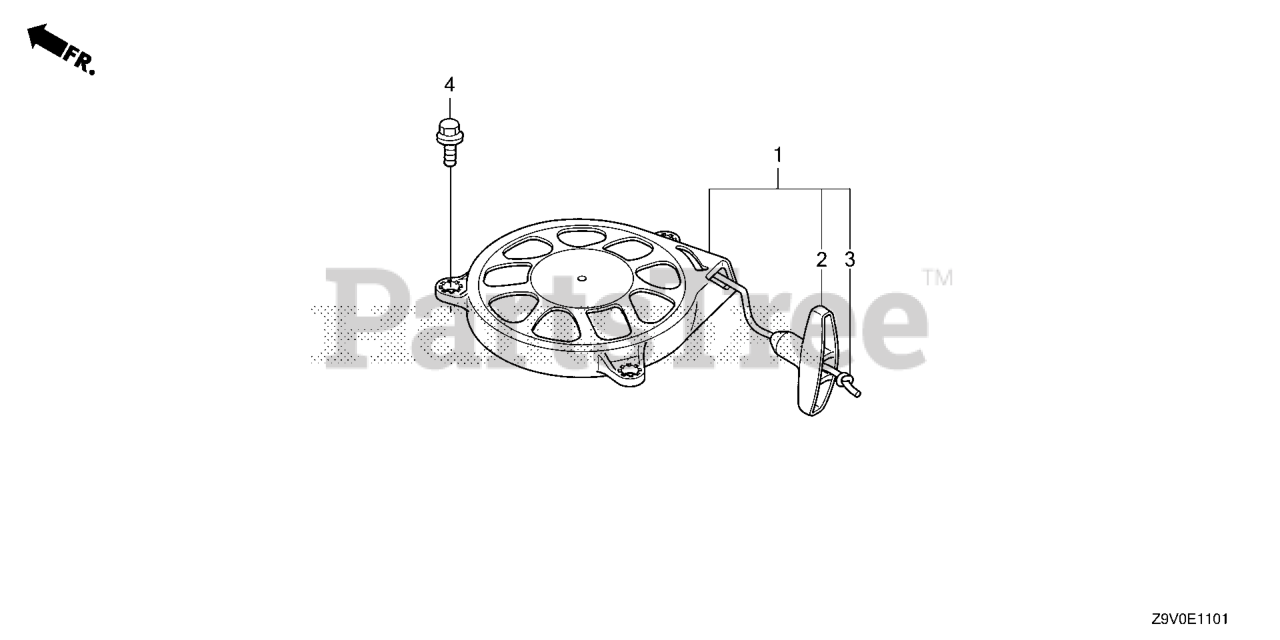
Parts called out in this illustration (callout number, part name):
1	STARTER ASSY., RECOIL (SHORT ROPE)
2	KNOB, RECOIL STARTER
3	ROPE, RECOIL STARTER (#3.5X52")
4	BOLT, FLANGE (6X14)
